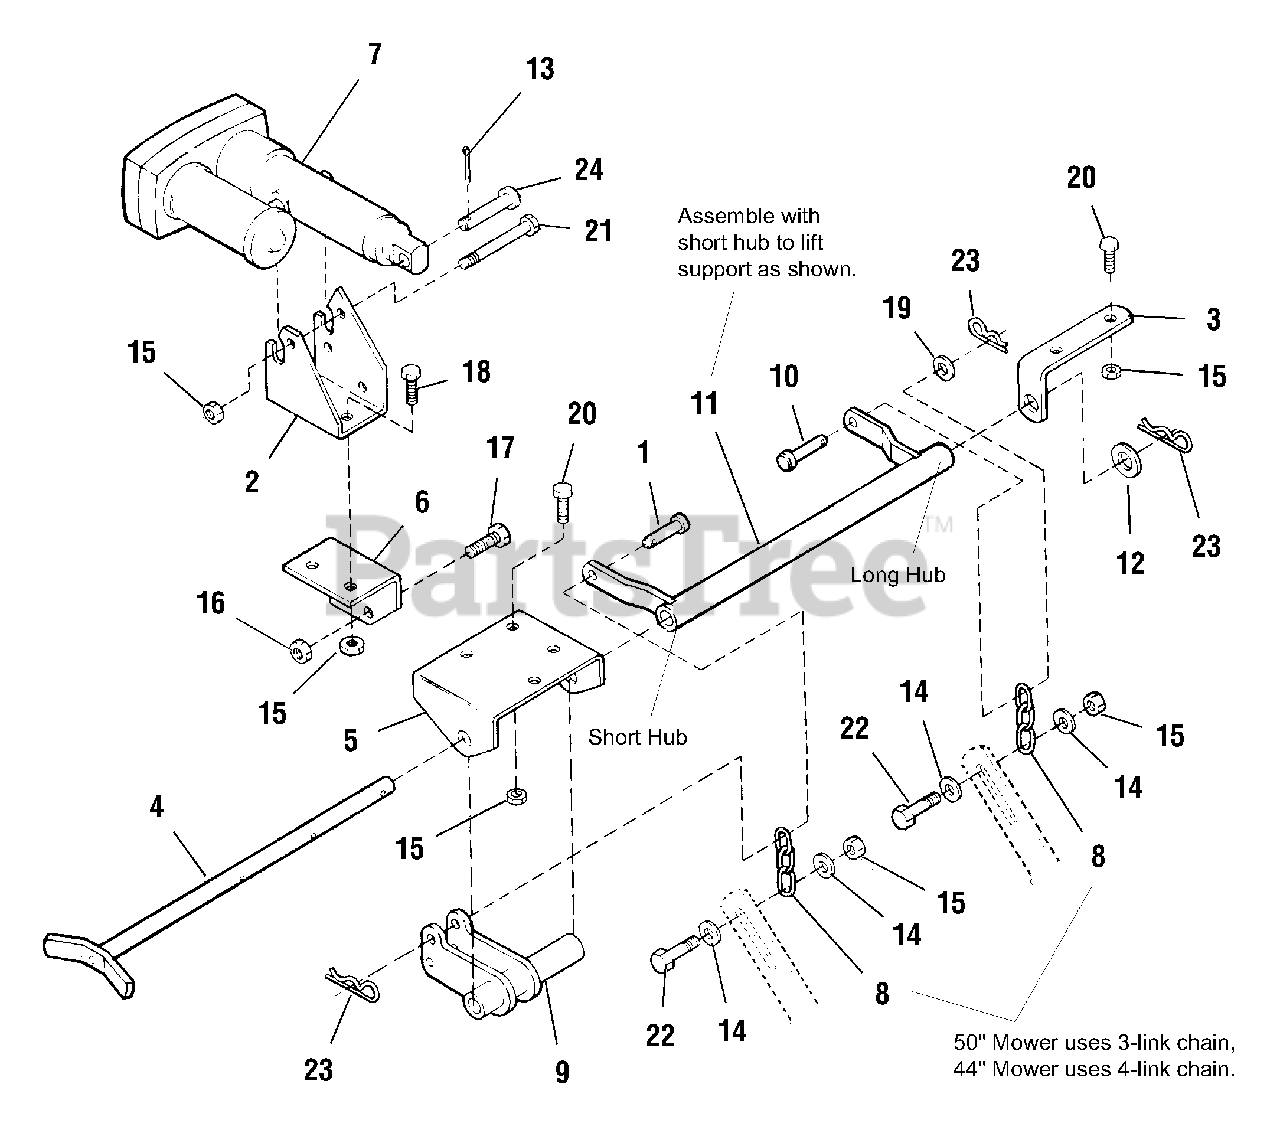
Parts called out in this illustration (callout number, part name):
1	PIN, Clevis
2	BRACKET, Actuator
3	LIFT, Pivot Bracket
4	SHAFT ASSY.
5	SUPPORT, Lift
6	SUPPORT, Actuator
7	POWER LIFT ASSY.
8	CHAIN, 3-Link
8	CHAIN, 4-Link
9	LIFT ARM ASSY.
10	PIN, Clevis
11	LIFT TUBE ASSY.
12	WASHER, Plain
13	PIN, Cotter
14	WASHER, Plain
15	NUT, Hex, Lock, ESNA, 5/16-18
16	NUT, Hex, Lock, ESNA, 3/8-16
17	CAPSCREW, Hex Hd., Whizlock, 3/8-16 x 1
18	CAPSCREW, Hex Hd., 5/16-18 x 1
19	WASHER, Plain
20	CAPSCREW, Hex Hd., 5/16-18 x 7/8
21	CAPSCREW, Hex Hd., 5/16-18 x 3-1/4
22	CAPSCREW, Hex Hd., 5/16-18 x 1-1/2
23	CLIP, Hair Pin (Large)
24	PIN
